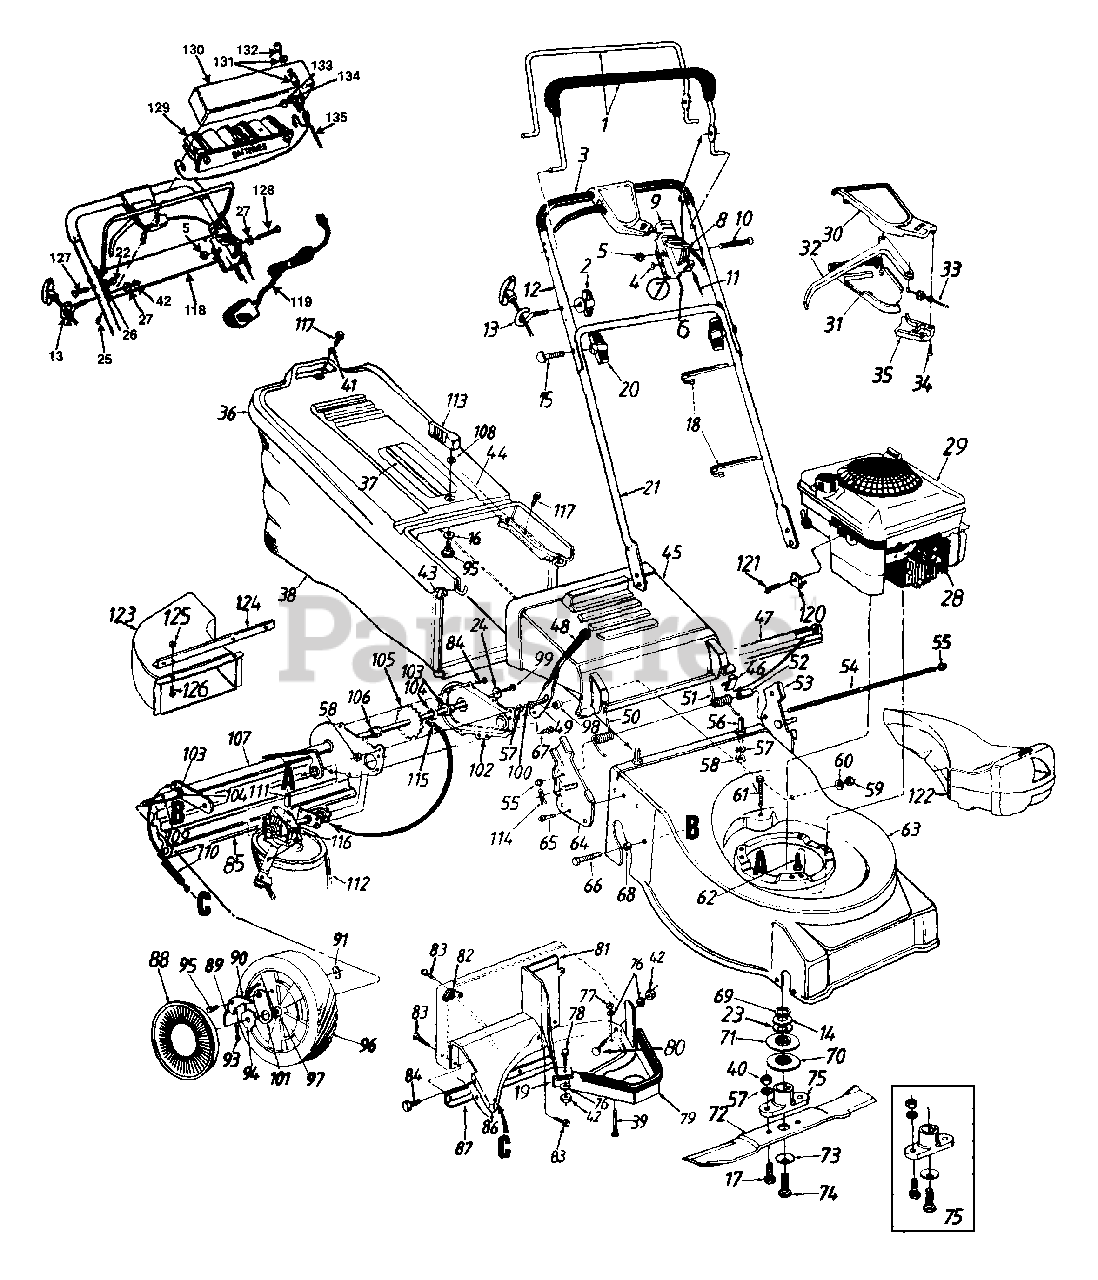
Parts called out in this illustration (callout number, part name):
2	Handle Knob 1/4-20 Thd.
3	Foam Grip
4	Spr. Wash. .66" I.D.
5	Hex L-Nut 1/4 - 20 Thd.
6	Throttle Cable - 55"
7	Throttle Box Comp.
8	Throttle Lever
9	Throttle Body
10	Oval C-Sunk Scr.
11	Control Cable - 40.5"
13	Rope Guide
14	Spr. Wash. .89" I.D.
15	Curved Hd. Bolt 5/16 - 18 x 2"
16	Bowed Washer
17	Hex Bolt 3/8 - 24 x 1" Lg.
18	Cable Tie
19	Stop Brkt.
20	Hand Knob
22	Hex Nut 5/16 - 18 Thd.
23	Fl-Wash. .88" I.D. x 1.85"
24	Bell-Wash. .265" I.D. x .75"
25	Truss Mach. Tap Scr. 1" Lg.
26	Bell-Wash. 5/16" I.D.
27	Bell-Wash. 1/4" I.D.
28	Spark Plug Boot
29	Engine
30	Control Cover Half - Upper
31	Control Cover Half - Lower
32	Control Lever
33	Drive Cable - 51" Lg.
34	Flat C-Sunk Hd. Tap Scr. #10 x .75" Lg.
35	Cable Mtg. Cap
36	Hardtop Bag Cover
37	Hardtop Handle
38	Grass Bag
39	Truss Mach. Scr. 1/4 - 20 x 1.0" Lg.
40	Hex Nut 3/8 - 24 Thd.
41	Fl-Wash. .281" I.D. x .62"
42	Hex Nut 1/4 - 20 Thd.
44	Rear Catcher Frame
45	Chute Deflector
46	Deflector Plug
47	Seal - Extrusion
49	Spring Lever
50	Torsion Spring - R.H.
51	Torsion Spring - L.H.
52	Spacer .255" I.D.
55	Cap Speed Nut
56	Shld. Pin 3/8 - 24 x 1.43" Lg.
57	L-Wash. 3/8" I.D.
58	Hex Jam Nut 3/8 - 24 Thd.
59	Hex L-Nut 3/8 - 24 Thd.
60	Bell-Wash. .38" I.D. x .88"
61	Hex Tap Scr. 1/4 - 20 x 1.5" Lg.
62	Hex Scr. 3/8 - 16 x 1" Lg.
63	21" Deck Ass'y.
66	Hex Tap Scr. 3/8 - 16 x .75" Lg.
67	Hex Tap Scr. 1/4 - 20 x .5" Lg.
68	Spacer.383" I.D.
69	Crankshaft Spacer
70	Pulley Half - Lower
71	Pulley Half - Upper
72	21" Blade
73	Bell-Wash. .39" I.D.
74	Hex Bolt 3/8 - 24 x 1.5" Lg.
75	Blade Adapter Kit
76	L-Wash. 1/4" I.D.
77	Hex Jam Nut 1/4 - 20 Thd.
78	Pan Head Mach. Scr. 1/4 - 20 x 1.0
79	Ext. Baffle
80	Carr. Bolt 1/4 - 20 x .50" Lg.
83	Torx Mach. AB-Tap Scr. 1/4 x .62" Lg.
84	Hex Tap Scr. 1/4 x .38" Lg.
85	Rear Flap
88	Hub Cap
89	Plastic Spring
90	Pawl .345" I.D.- R.H.
91	Weld Top L-Nut 1/4 - 20 Thd.
93	Cotter Pin 1/8" Dia.
94	Ratchet Wheel 1.62" O.D.
95	Shld. Bolt .342" Dia. x .268"
96	Rear Wheel Ass'y. Comp.
97	Bearing 1/2" I.D.
98	Shld. Spacer .50" Dia.
99	Hex Bolt 1/4 - 20 x .62" Lg. (Gr. 5)
100	Shld. Pin 3/8 - 24 x 1.43" Lg.
101	Pawl Plate
104	Fl-Wash. .531" I.D. x .93"
105	Rear Axle Ass'y.
106	Hex Flange Bearing
109	Spacer .513" I.D.
110	Extension Spring 3.8" Lg.
111	Spacer .325" I.D.
112	V-Belt
113	Grass Catcher Locking Knob
114	Internal Cotter Pin 5/16" Dia.
115	#48 Chain .50" Pitch x 30 Links
116	Transmission Comp.
117	Hex AB-Tap Scr. 1/4 x .62" Lg.
120	Cable Clamp
121	Hex Self-Tap Scr. #10 - 32 x .62" Lg.
122	Mulching Plug
123	Chute Deflector
125	Hex L-Nut 1/4 - 20 Thd.
126	Mach. Scr. 1/4 - 20 x .5" Lg.
127	Curved Carr. Bolt 5/16 - 18 x 1
128	Hex Bolt 1/4 - 20 x 2" Lg.
129	Battery Pack 12 Volt
130	Battery Tray
131	Ignition Switch
132	Ignition Key
133	Fuse Holder
134	Plug
135	Wire Harness
